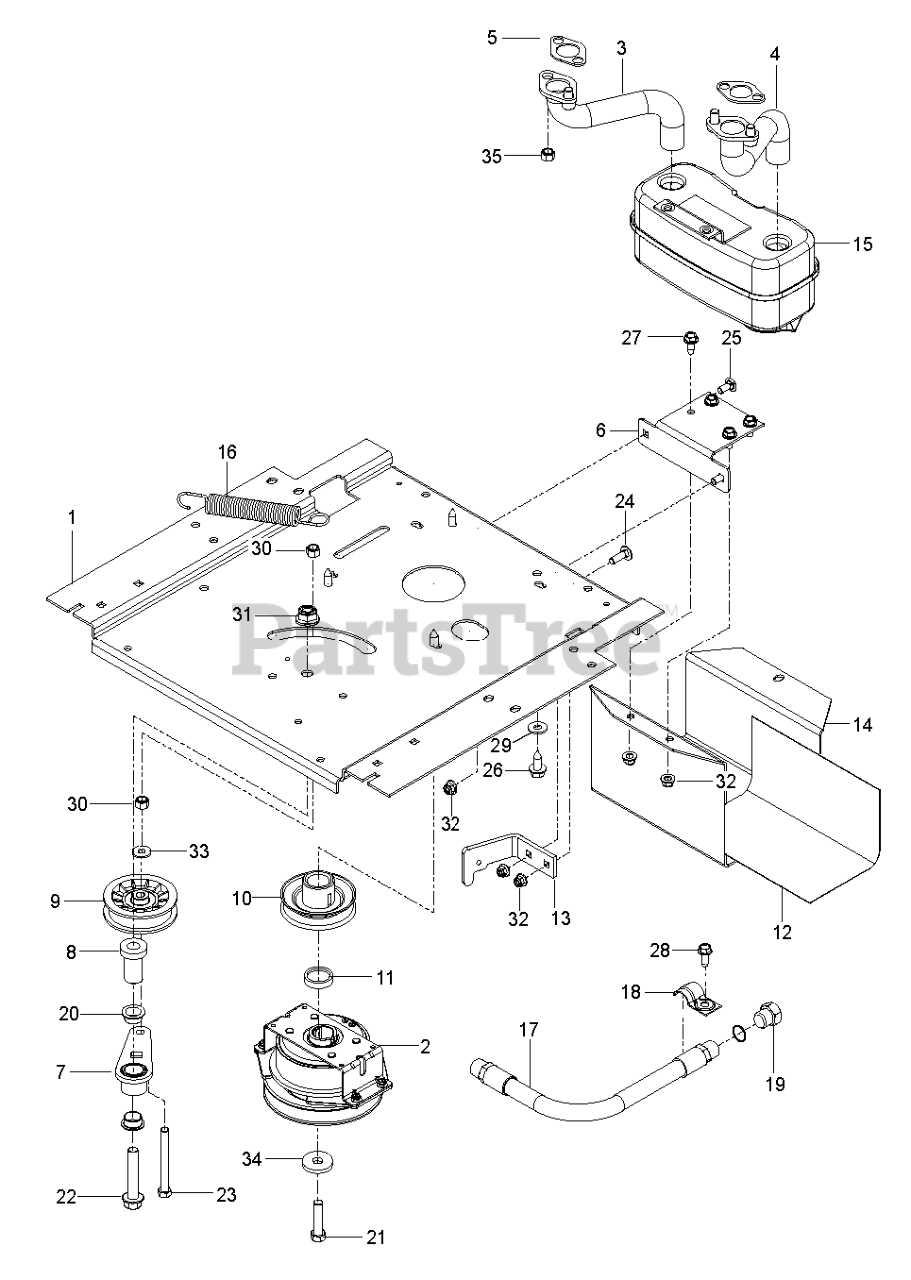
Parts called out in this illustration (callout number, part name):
1	PLATE ENGINE; RZ, 23IN BLACK
2	CLUTCH.OGURA.5.0PD.GT1.5A-EH07
3	TUBE.EXHAUST.RH.FR961/FR730
4	TUBE.EXHAUST.LH.FR961/FR730
6	BRACKET MUFFLER MS431BLK
7	ARM IDLER
8	SPINDLE.IDLER
9	PULLEY, IDLER RAKE & ZTR
10	PULLEY.ENGINE
11	SPACER.SPACER.625 W/OGURA.LCC
12	HEAT SHIELD
13	CLUTCH.STOP.OGURA LCC.BLACK
14	GUARD.MUFFLER.WO.TOW.HITCHX431
15	MUFFLER ASM TWIN
16	SPRING, DECK DRIVE
17	HOSE.ASSEMBLY.OIL.DRAIN
19	PLUG OIL DRAIN
20	BEARING.FLANGED.PLASTIC.3/4ID
21	CLUTCH BOLT7/16-20X2.5 GR524HR
22	BOLT.FLANGE.1/2-13 X 2.75.GRD5
23	HCS 3/8-16X3-1/2 TAPBLT GR5 ZD
24	RHSNB 5/16C X 1
25	BOLT 5/16C X 3/4" CARRIAGE
26	BOLT
27	SCREW.THDROL.5/16-18X3/4.TTY
28	SCR 1/4-20X5/8 HEX SELF TAP ZD
29	SLW 3/8 STD
30	NUT 3/8-16 NYLOC
31	NUT, 1/2-13 HEX FLG NYLOC ZD
32	5/16-18 NYLOC FLANGE NUT
33	WASHER 5/16 FLAT
35	NUT.HEX.FLANGE.TOPLOCK
